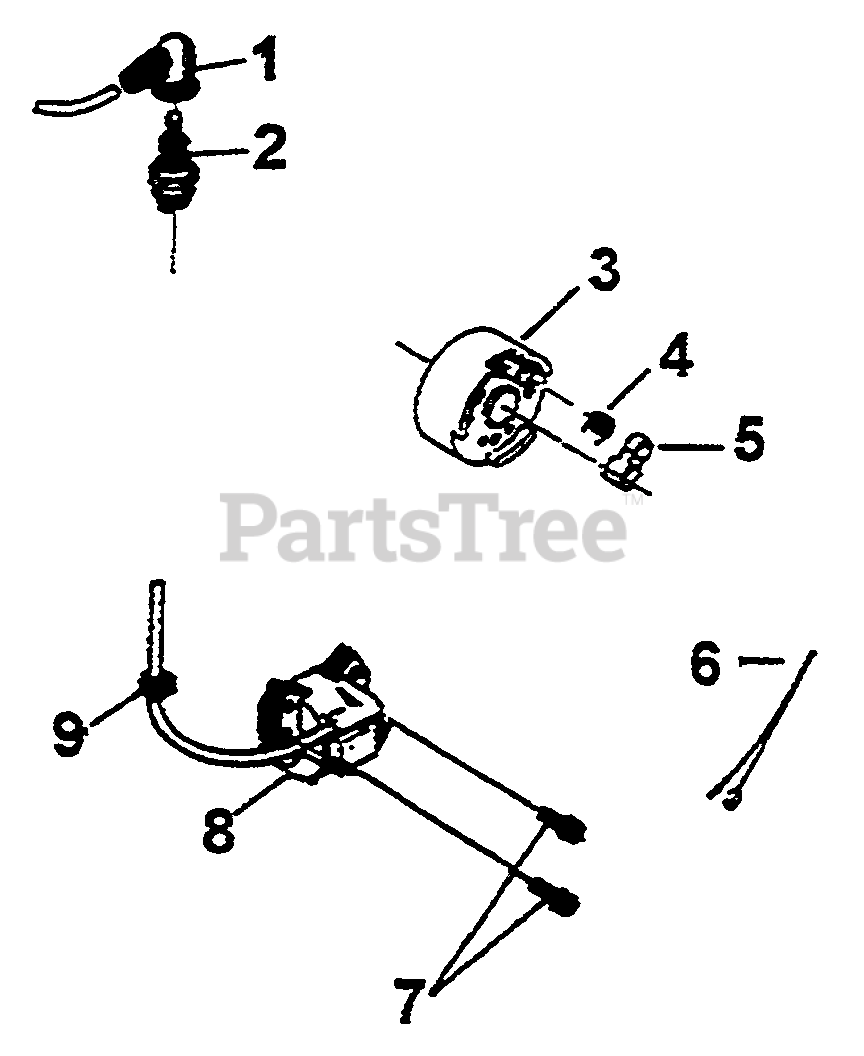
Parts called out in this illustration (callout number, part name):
1	CAP, PLUG
2	SPARK PLUG
6	HARNESS, WIRE
7	BOLT & WASHER
8	COIL, IGNITION
